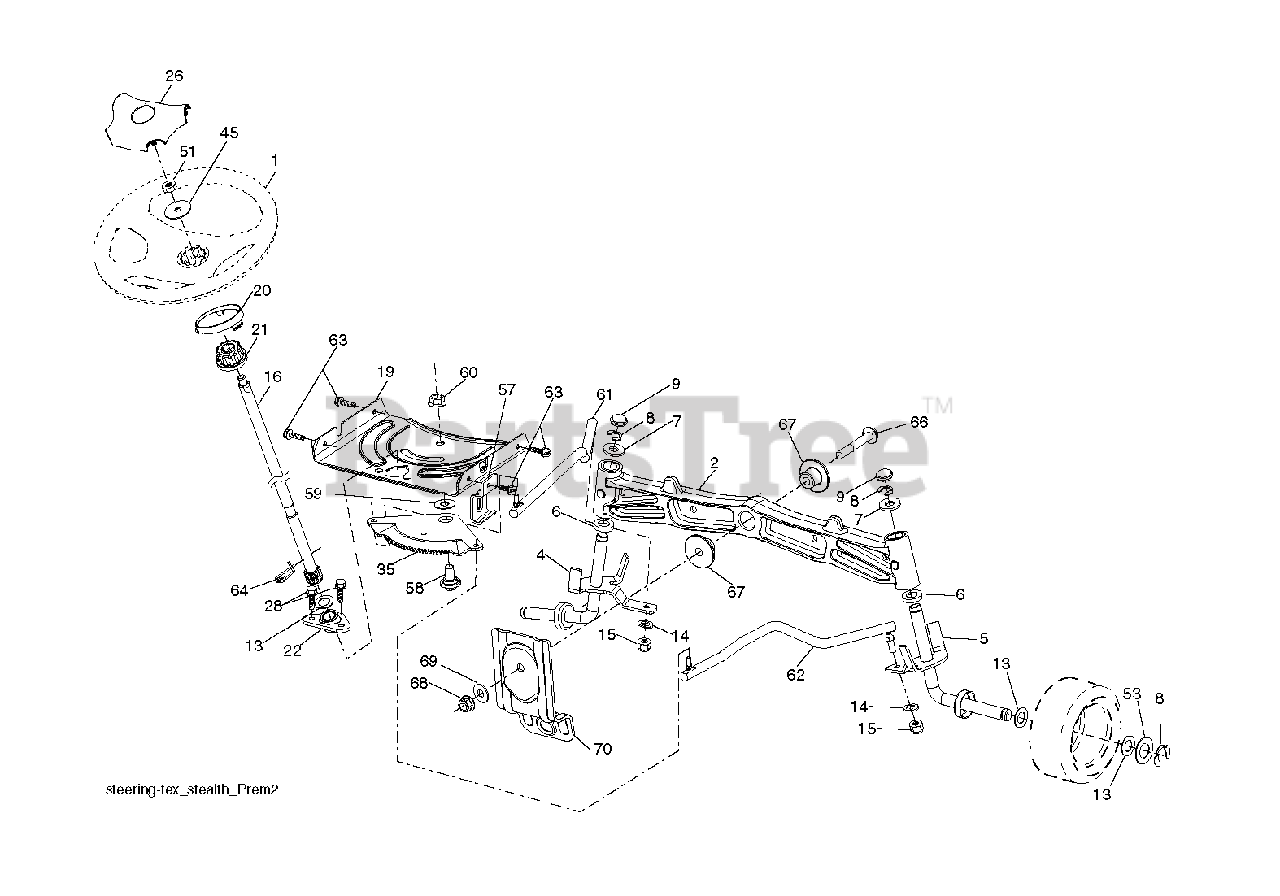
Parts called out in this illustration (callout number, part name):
1	WHEEL.STEERING.PREM.2.BLK
2	AXLE.CAST.IRON
4	SPINDLE.WELDED.LH.16"TEX
5	SPINDLE.WELDED.RH.16"TEX
8	RING CLIP
9	CAP.SPINDLE
14	WASHER, LOCK 3/8
15	NUT CROWNLOCK 3/8-24
16	SHAFT.STEER.STEALTH.DD
19	PLATE.STEER.DDL.NLT/NG
20	BOOT.STEERING.
21	ADAPTER, WHEEL STNG..
22	BUSHING.ASM.STEERING.A
26	INSERT.CAP.STRG.WH.BLACK
28	SCREW, 3/8-16X3/4
35	GEAR.SECTOR.PLATE.DDL.
45	WASHER.11/32
51	NUT.HEX.1/2-20
53	WASHER.HARDENED
57	BRKT.UPSTOP.GT/LT.TEX
58	BOLT.SHOULDER.SECTOR.P
59	WASHER.THURST.SECTOR.S
60	NUT FLANGE LOCK 5/8-11
61	DRAGLINK.LH.BALLSTUD.D
62	DRAGLINK.RH.BALLSTUD.D
63	SCREW
64	RETAINER.CLIP.SPRING.S
66	BOLT HEX FGHD 7/16-14 X 3 SERR
67	BUSHING.PM.FRONT AXLE
68	NUT.LOCK.FLANGE.7/16
69	WASHER.1.5X.505X.118
70	BRKT.DECK.SUSPENSION.F
